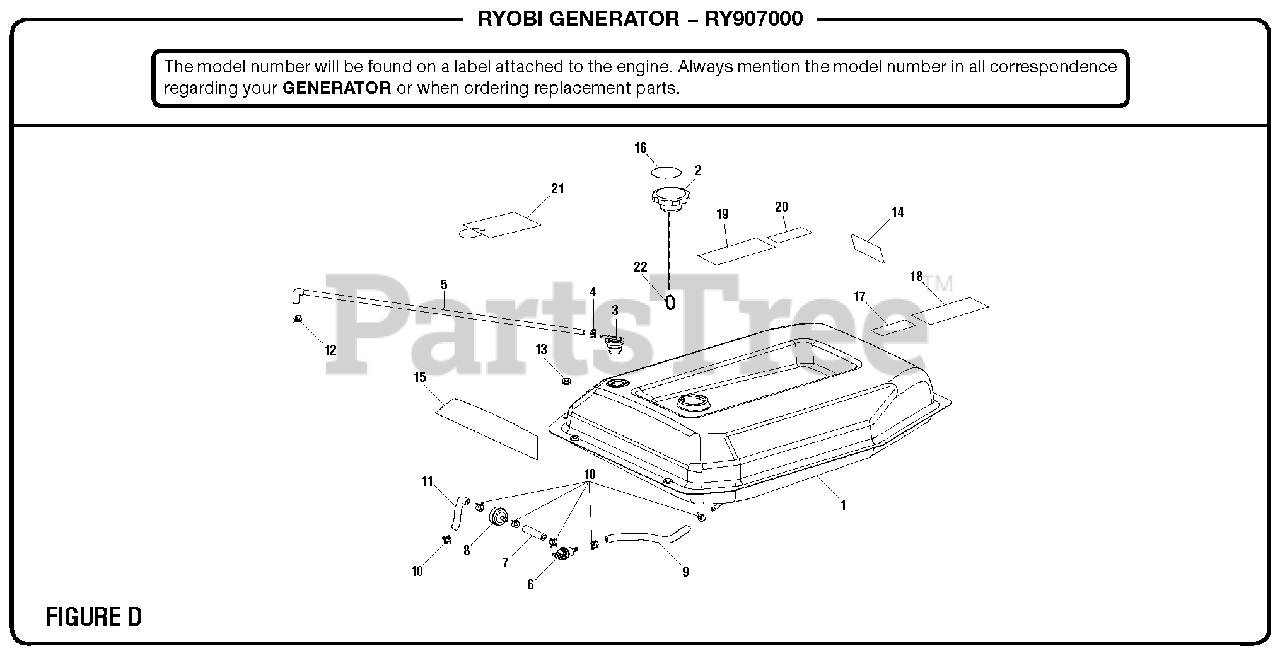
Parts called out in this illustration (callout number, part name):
1	Fuel Tank
3	Vapor Vent
4	Hose Clamp (10.3 mm)
5	Vapor Hose
6	Fuel Shut Off Valve
7	Fuel Hose (55 mm)
8	Fuel Filter
9	Fuel Hose (175 mm)
10	Hose Clamp (1/2 in.)
11	Fuel Hose (185 mm)
12	Hose Clamp (3/8 in.)
14	Combustion Label
15	Logo Label
16	Fuel Stabilizer Label (Eng.)
17	Fuel Stabilizer Label (Fr./Sp.)
18	CPSC Label
19	Warning Label
20	E85 Label
21	Danger Hang Tag
22	Ring Clip
